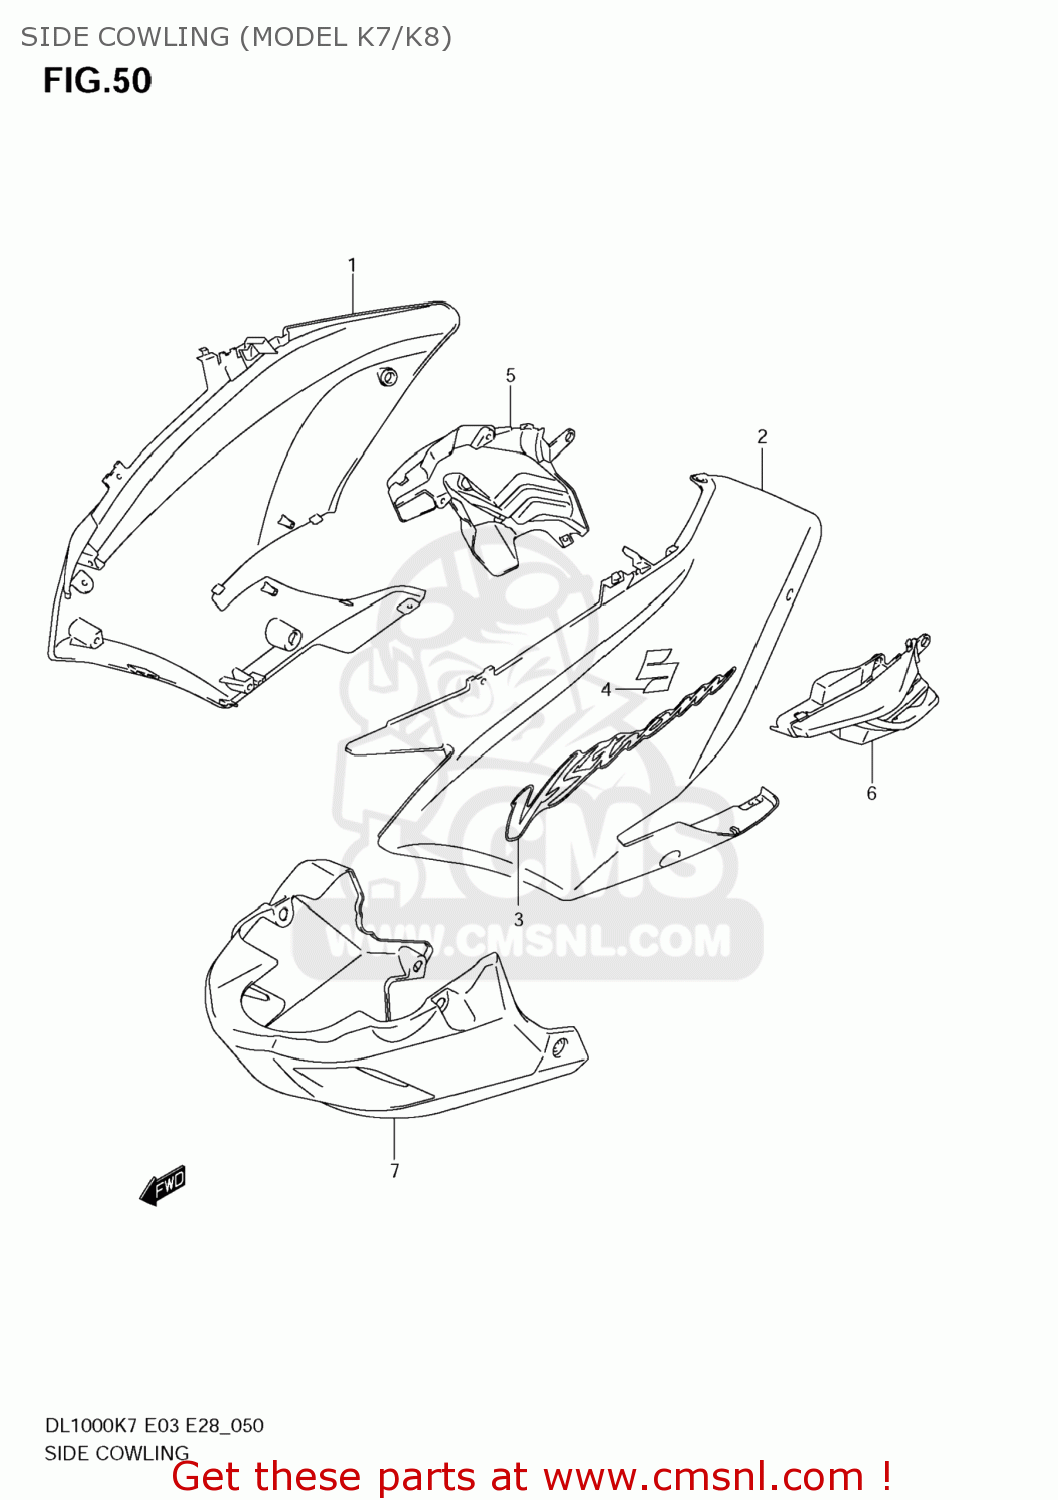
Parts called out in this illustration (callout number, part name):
1	COWLING ASSY,SIDE,R
2	COWLING ASSY,SIDE,L
3	EMBLEM,COWLING SIDE
4	EMBLEM,S
5	COVER,SIDE COWL,R(BLACK)
6	COVER,SIDE COWL,L(BLACK)
7	COWLING,UNDER
